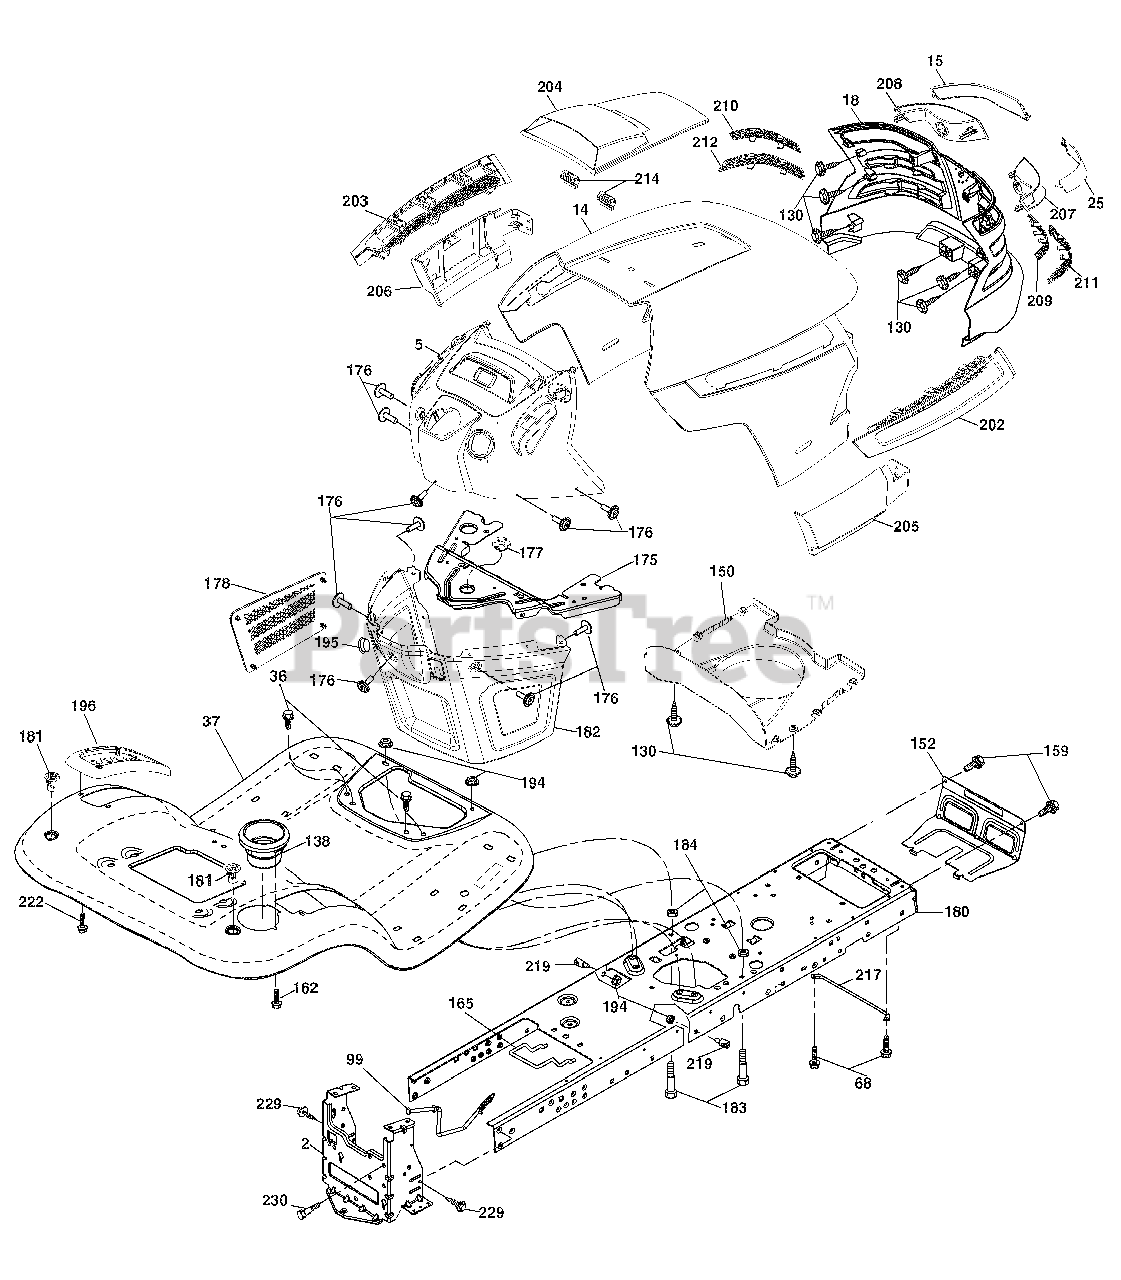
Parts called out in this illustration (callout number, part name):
14	Hood
18	Grille/Lens Asm.
36	Screw 5/16-18 x 3/4
37	Fender
68	Screw Thdrol 5/16-18 x 1/2
99	Rod Asm Bypass
130	Screw 10 x 3/4 Single Lead-Hex
138	Cupholder
152	Shield Browning
159	Screw 3/8-16 x 3/4
165	Support Tank Rear
175	Crossmember
176	Screw 10-24 x 5/8
177	Bushing Steering
178	Cargo Net Asm.
180	Chassis
181	Bushing Mtg. Fender Crgo
182	Dash Lower
183	Bolt Fin Hex 5/16-18 unc x 1-1/4
184	Spacer Fender
194	Nut Lock Hex Flange 5/16-18
195	Plug Hole Dash Lower
196	Console Asm. Deck Lift
202	Vent Side Hood RH
203	Vent Side Hood LH
204	Vent Top Hood
205	Skirt Hood Side RH
206	Skirt Hood Side LH
209	Insert Hex Top RH
210	Insert Hex Top Lh
211	Insert Hex Bottom RH
212	Insert Hex Bottom LH
214	Clip Retainer Tinner
217	Rod Pivot
219	Stud Fastner
222	Screw Thdrol 1/4-20 x 5/8
229	Screw Hexwsh Thdr 3/8-16 x 3/4
230	Bolt Shoulder 5/16-18
